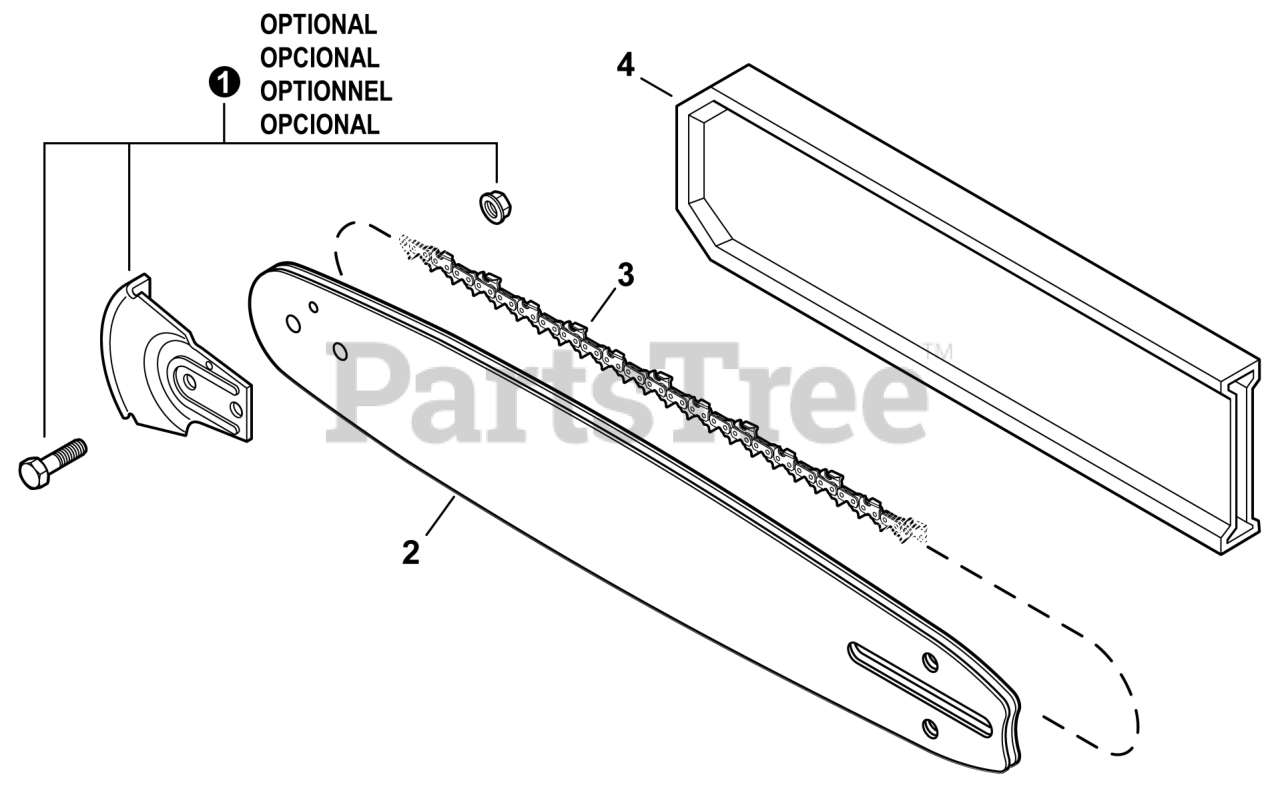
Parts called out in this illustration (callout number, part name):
1	KICK GUARD KIT
2	GUIDE BAR, 16"
3	SAW CHAIN 16"
4	SCABBARD 16"
